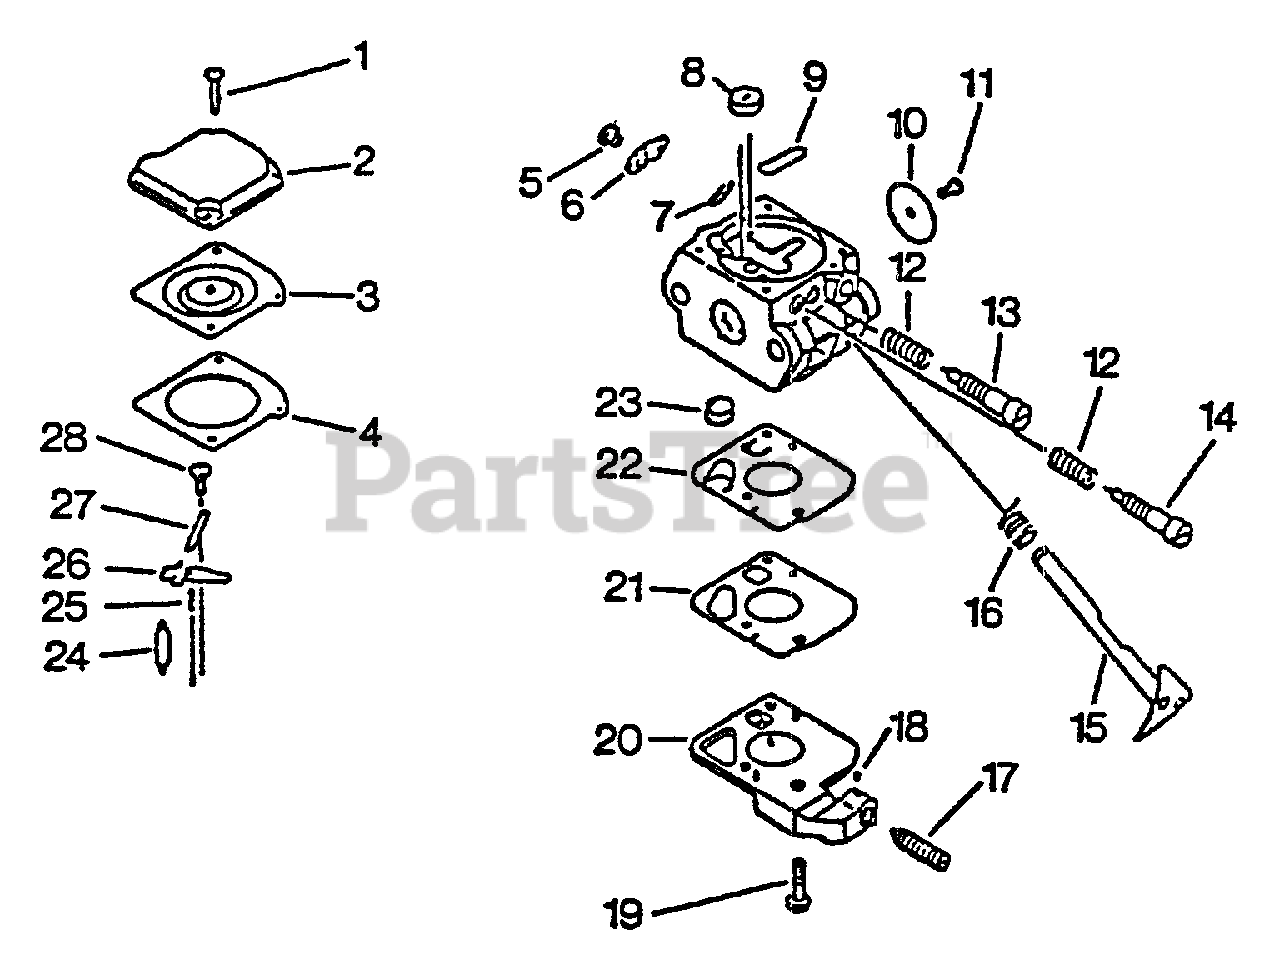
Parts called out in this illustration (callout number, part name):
2	COVER, DIAPHRAGM
3	DIAPHRAGM
4	GASKET, METERING
6	LEVER, THROTTLE
8	NOZZLE, CHECK VALVE
9	PLUG, WELCH
10	VALVE, THROTTLE
11	SCREW
12	SPRING, NEEDLE
13	NEEDLE, HIGH SPEED
14	NEEDLE, LOW SPEED
15	SHAFT, THROTTLE
16	SPRING, THROTTLE RETURN
17	SCREW, IDLE ADJUST
18	PIECE, FRICTION
20	COVER, PUMP
21	GASKET, PUMP
22	DIAPHRAGM, PUMP
23	STRAINER
24	VALVE, NEEDLE
25	SPRING
26	LEVER, METERING
27	PIN, METERING LEVER
